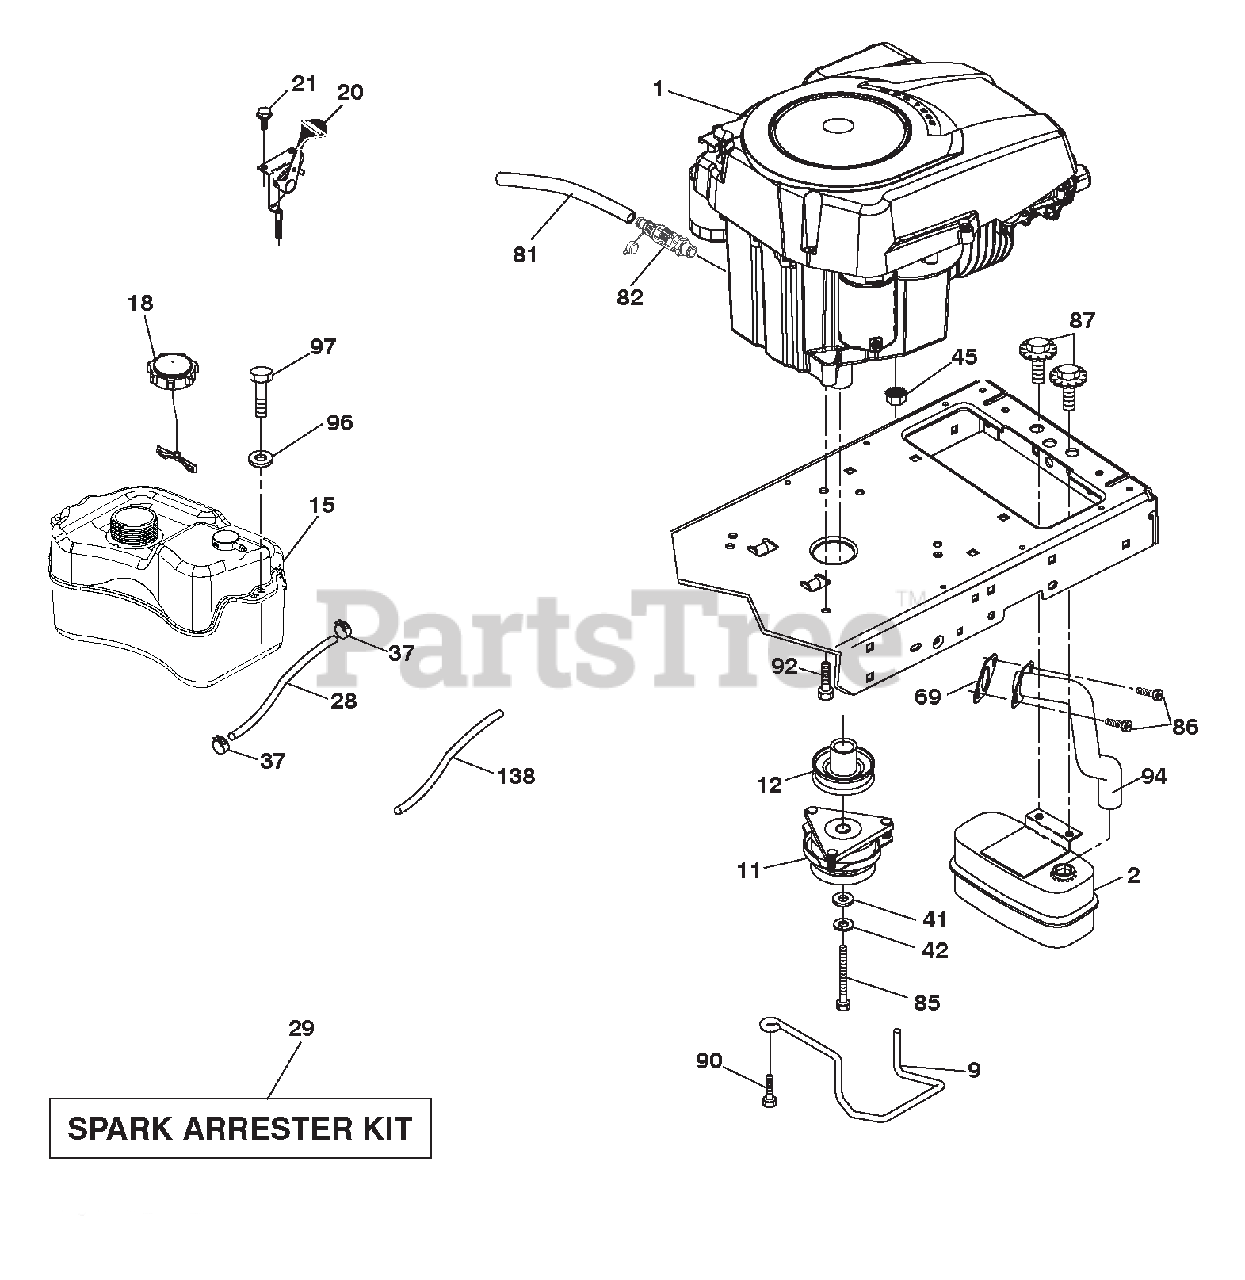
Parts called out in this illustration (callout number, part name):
1	ENGINE.KOHLER.MODEL.SV600-3229
2	MUFFLER
9	KEEPER.BELT.ENGINE.4.25"NSTG
11	CLUTCH OGURA
12	PULLEY.ENGINE.TUFFTORQE.1"CRK.
15	TANK.FUEL.2.5.GAL.
18	CAP.FUEL
20	CONTROL THROTTLE/CHOKE
28	LINE.FUEL.22"FRONT.EMIS.CA.LP
29	KIT.SPARK ARRESTOR(392390 B&S)
37	CLAMP.HOSE.BLK.
41	WASHER.1-1/2 ODX15/32 IDX.250
42	WASHER.LOCK.HVY HLCL.SPR.7/16
45	Nut, Keps Hex 1/4-20 unc
69	GASKET.KOHLER.SV.I.
81	TUBE.DRAIN.OIL.EASY
82	VALVE OIL DRAIN
85	BOLT.HEX.7/16-20X4XGR5-1.5THR.
86	SCREW SOCKET HEAD 5/16-18 X 1
87	BOLT.5/16-18UNCX3/4 W/SEMS.BLK
90	SCREW.3/8-16X1.SMGML.TAP/R.BLK
92	SCREW.3/8-16 X 1.SMGML.TAP/R
94	TUBE.EXHAUST.KOHL.COURAGE
96	WASHER.9/32 X 7/8 X 16GA.
97	SCREW.HEXWSH.THDROL.1/4-20X3/4
138	PURGE.LINE.CARB
